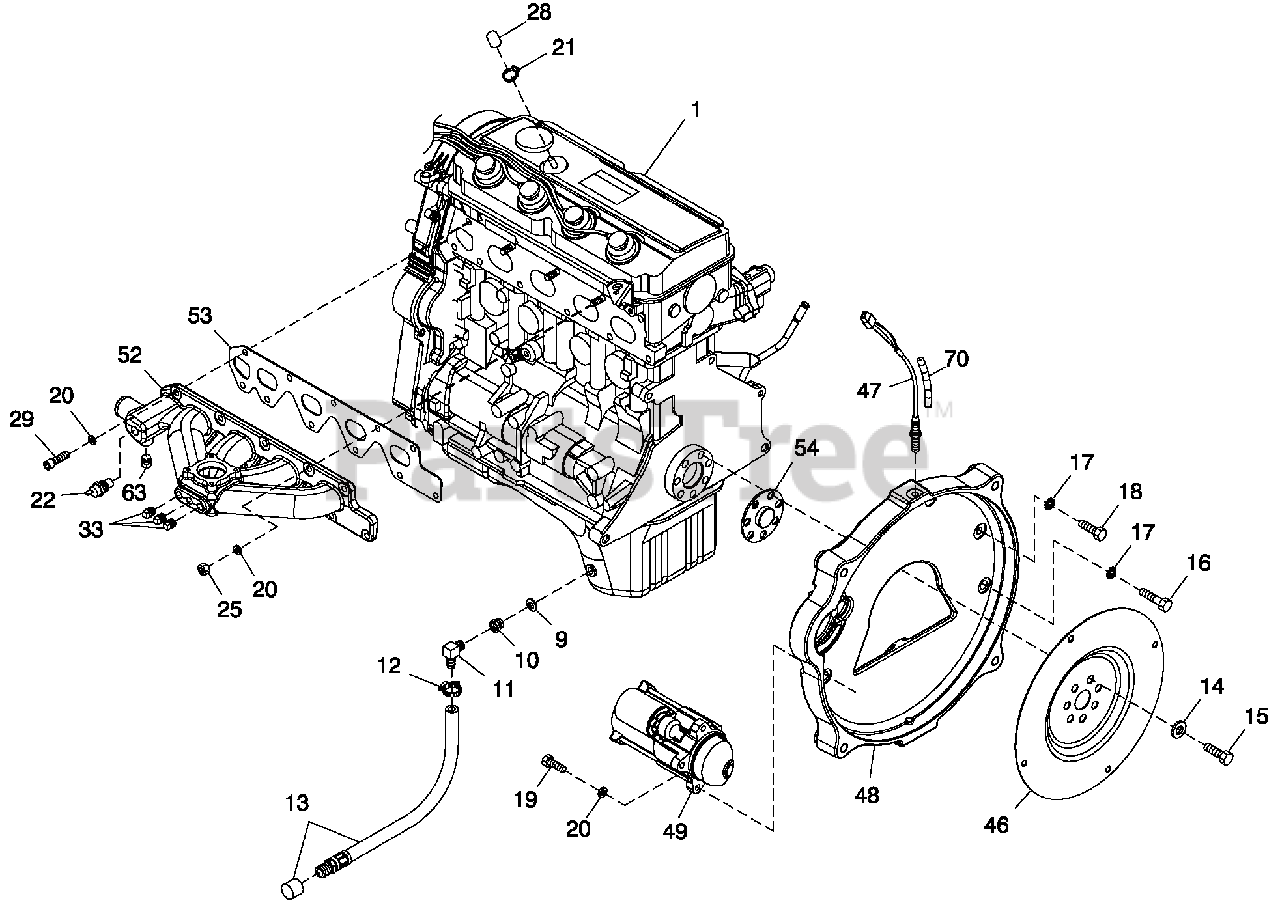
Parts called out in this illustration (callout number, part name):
1	ENGINE 2 .4 L G 2
12	CLAM P HOSE .38-.87
13	HOSE DRAIN ASSY 28"
14	WA S H E R FLAT .531 ID X 1.062 OD
15	SCREW HHC M12-1.25 X 20 G10.9
16	SCREW HHC M10-1.25 X 45 G8.8
17	W A S H E R SH AKE PROOF EXT 7/16 STL
18	SCREW HHC M10-1.25 X 30 G8.8
19	SCREW SHC M 8 -1 .2 5 X 3 0 G 1 2 .9
20	W A S H E R LOC K M8-5/16
21	CLAM P HOSE #6 .43-.78
22	SWITCH HI-TEMP 245D X 3/8 N PT (R-PANEL)
25	NUT HEX M8-1.25 G8 CLEAR ZINC
26	W ASH ER FLAT 3/8-M10 ZINC
27	ASSY DI P S TIC K TUBE 2.4 G2
28	C A P ANTIFREEZE RUBBER 9.5DIA
29	SCREW SHC M 8-1.25X 25 G12.9
33	PLUG STD PI PE 1/4 STEEL SQ HD
46	FLEX PLATE 2 POLE 2 .4 L G 2
47	ASSY MAG PICKUP(3/8-24 MALE)
48	AD A PTE R ENGINE 2.4L MACHINE
49	MOTOR STAR TER
52	M ANIFOLD INTAKE
53	G ASKET INTAKE MANIFOLD
54	S PACER 2.4L G2 FLEX PLATE
63	PLUG STD PI PE 3/8 STEEL SQ HD
70	CONDUIT FLEX .25"ID
